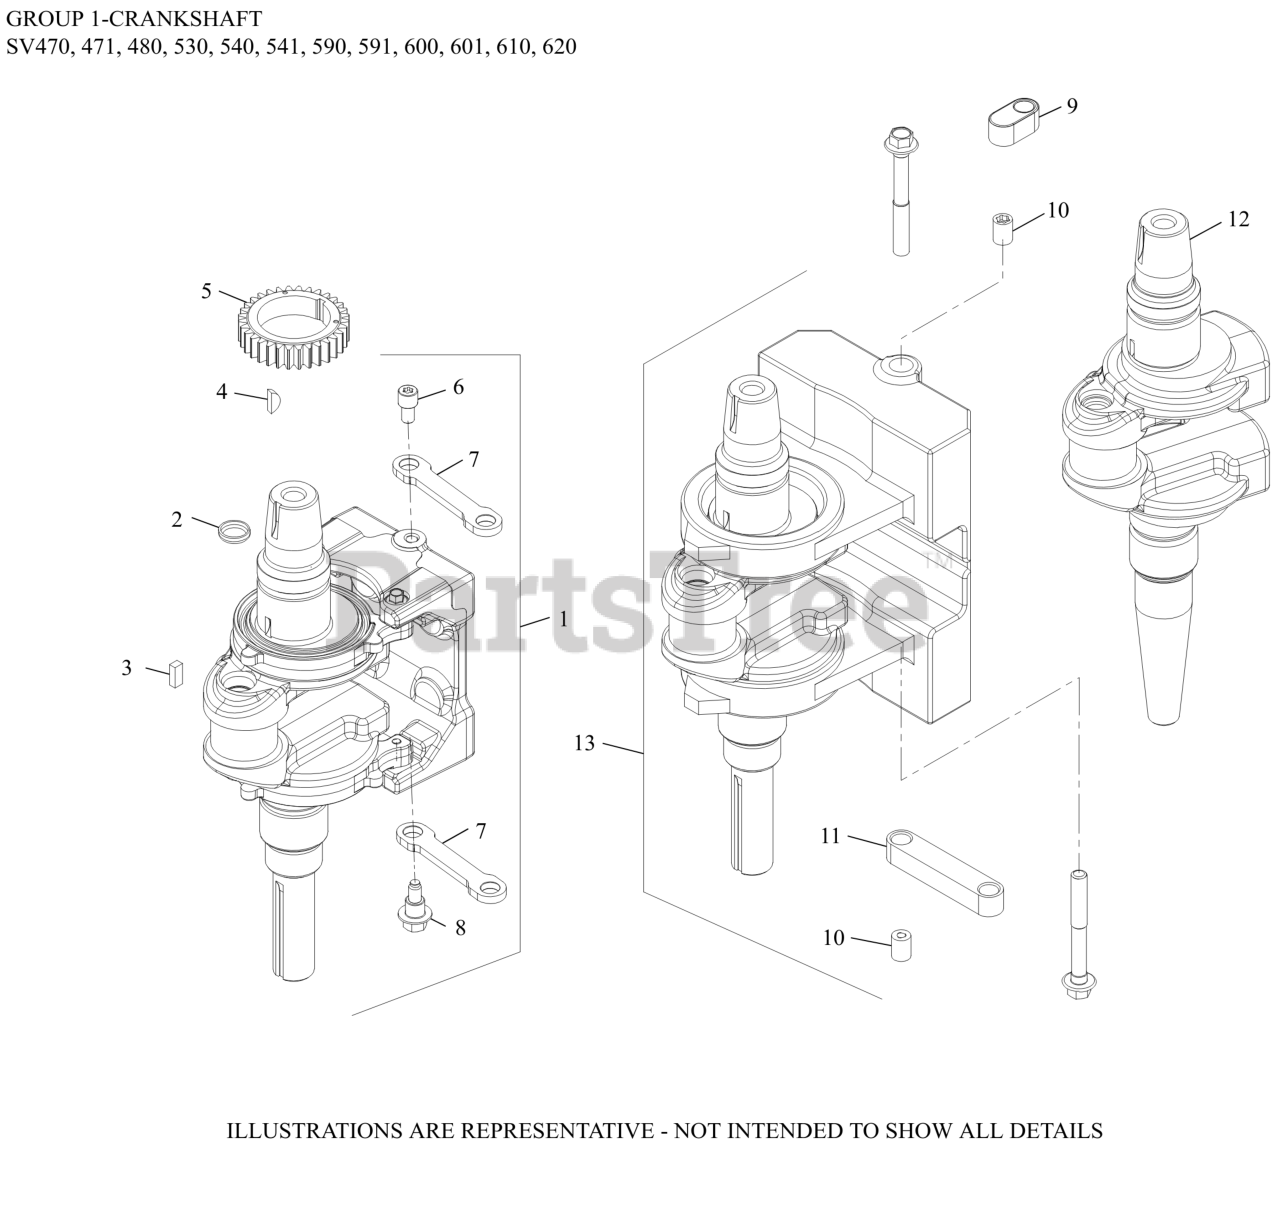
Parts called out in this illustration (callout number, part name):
1	KIT, CRANKSHAFT
2	PLUG, CUP
4	KEY, 3/16" X 5/8"
5	GEAR, CRANKSHAFT-(#DSC)
10	KIT, GUIDE PIN - DISCONTINUED
11	LINKAGE, BALANCE WEIGHT-USE 20 186 04-S
12	KIT, CRANKSHAFT - DISCONTINUED
